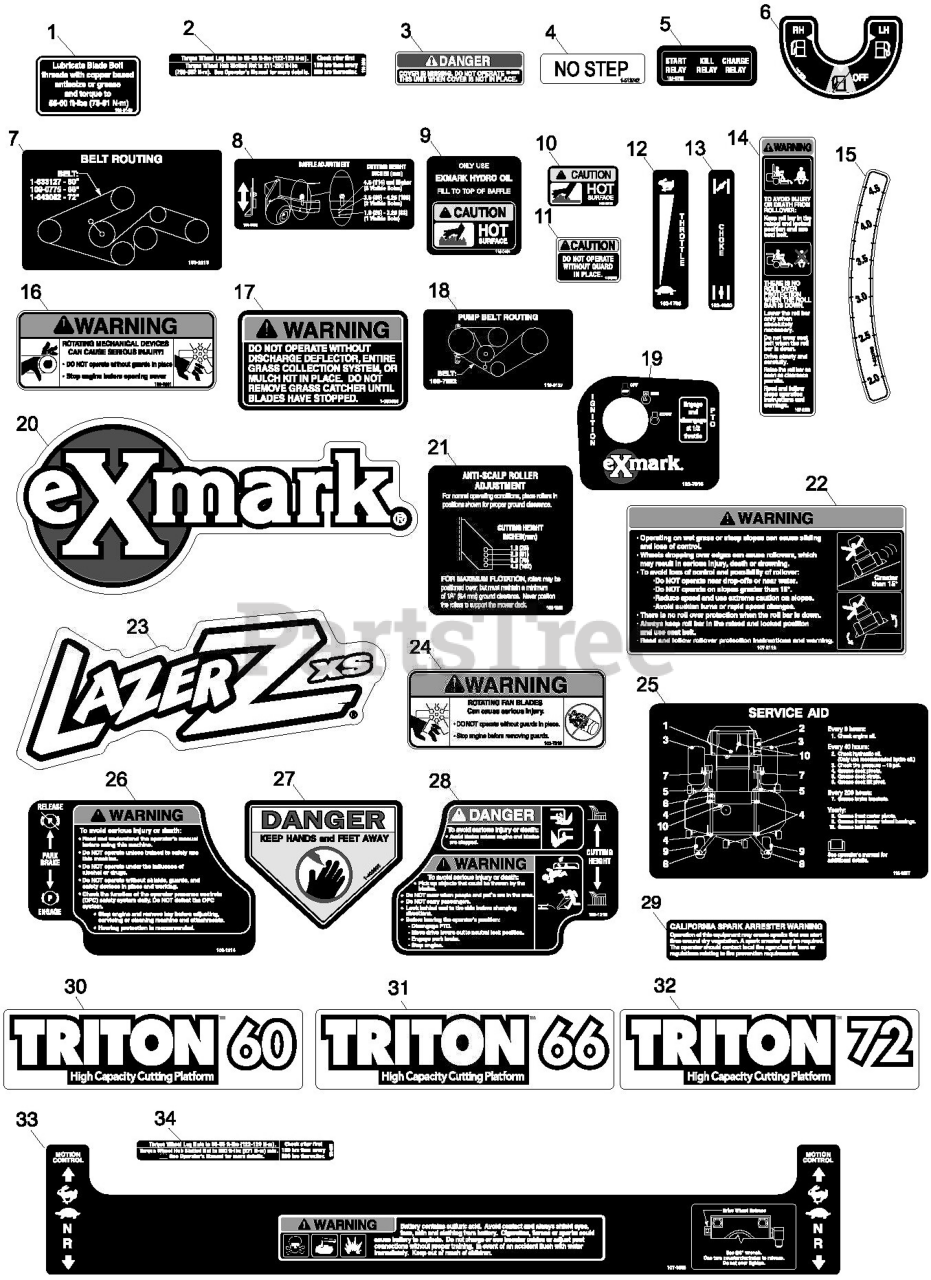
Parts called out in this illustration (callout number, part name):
1	DECAL,BOLT TORQUE
3	DECAL-COVER, MISSING
4	DECAL,NO STEP
5	DECAL,RELAY
6	DECAL-VALVE, FUEL
7	DECAL,BELT ROUTING
8	DECAL,BAFFLE ADJUSTMENT
9	DECAL-HYDRAULIC TANK
10	DECAL-CAUTION
11	DECAL-GUARD
12	DECAL,THROTTLE ONLY
13	DECAL,CHOKE
14	DECAL-WARNING, FOLDING RO
15	DECAL-HEIGHT, DECK
16	DECAL-DEVICES, ROTATING
17	DECAL-WARNING, DISCHARGE
18	DECAL,HYDRO BELT ROUTING
20	DECAL,EXMARK
21	DECAL,ANTISCALP
22	DECAL-WARNING
23	DECAL,LAZER XS MODEL
24	DECAL,PUMP FAN WARNING
25	DECAL, CHECK SERVICE
26	DECAL,PARK BRAKE
27	DECAL-DANGER
28	DECAL,DECK HEIGHT
29	DECAL-ARRESTER, SPARK
30	DECAL,TRITON 60
31	DECAL,TRITON 66
32	DECAL,TRITON 72
33	DECAL-CONSOLE, TOP
34	DECAL-HUB, WHEEL
